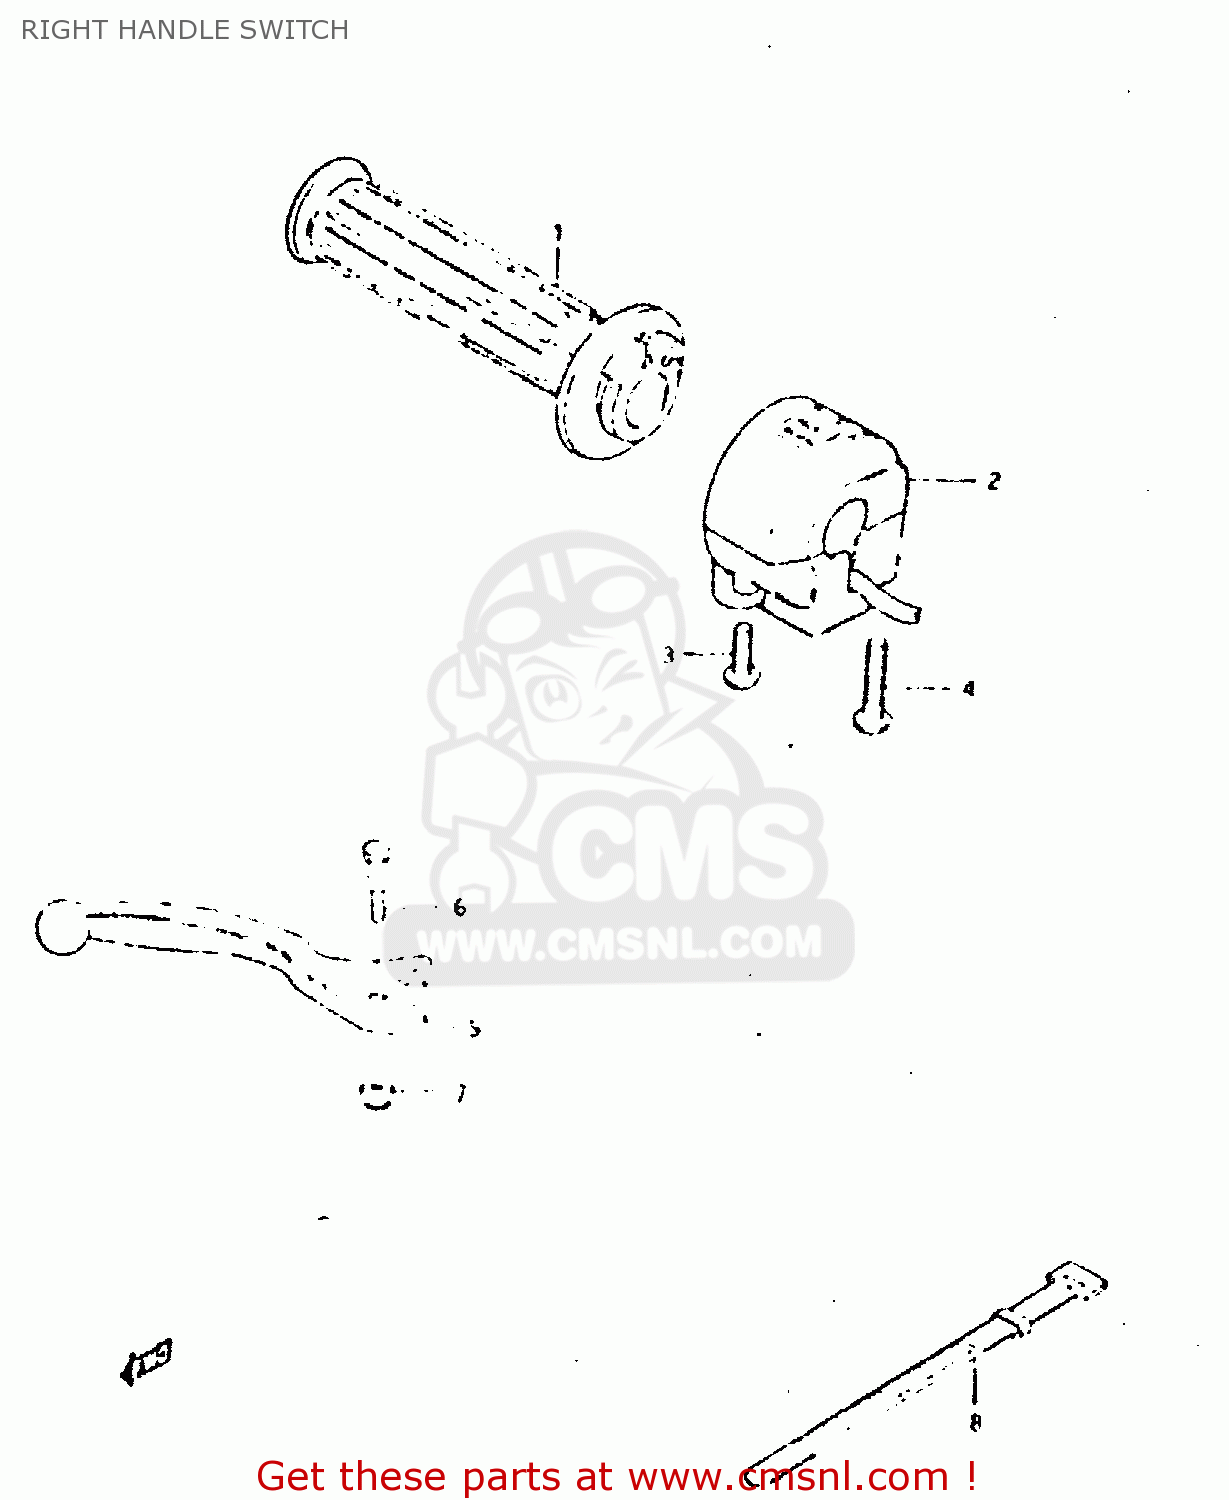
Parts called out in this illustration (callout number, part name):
1	GRIP,THROTTLE
2	SWITCH ASSY, HANDLE RH
3	SCREW
4	SCREW
5	LEVER,BRAKE
6	BOLT
7	NUT 6MM
8	CLAMP(L:120)
